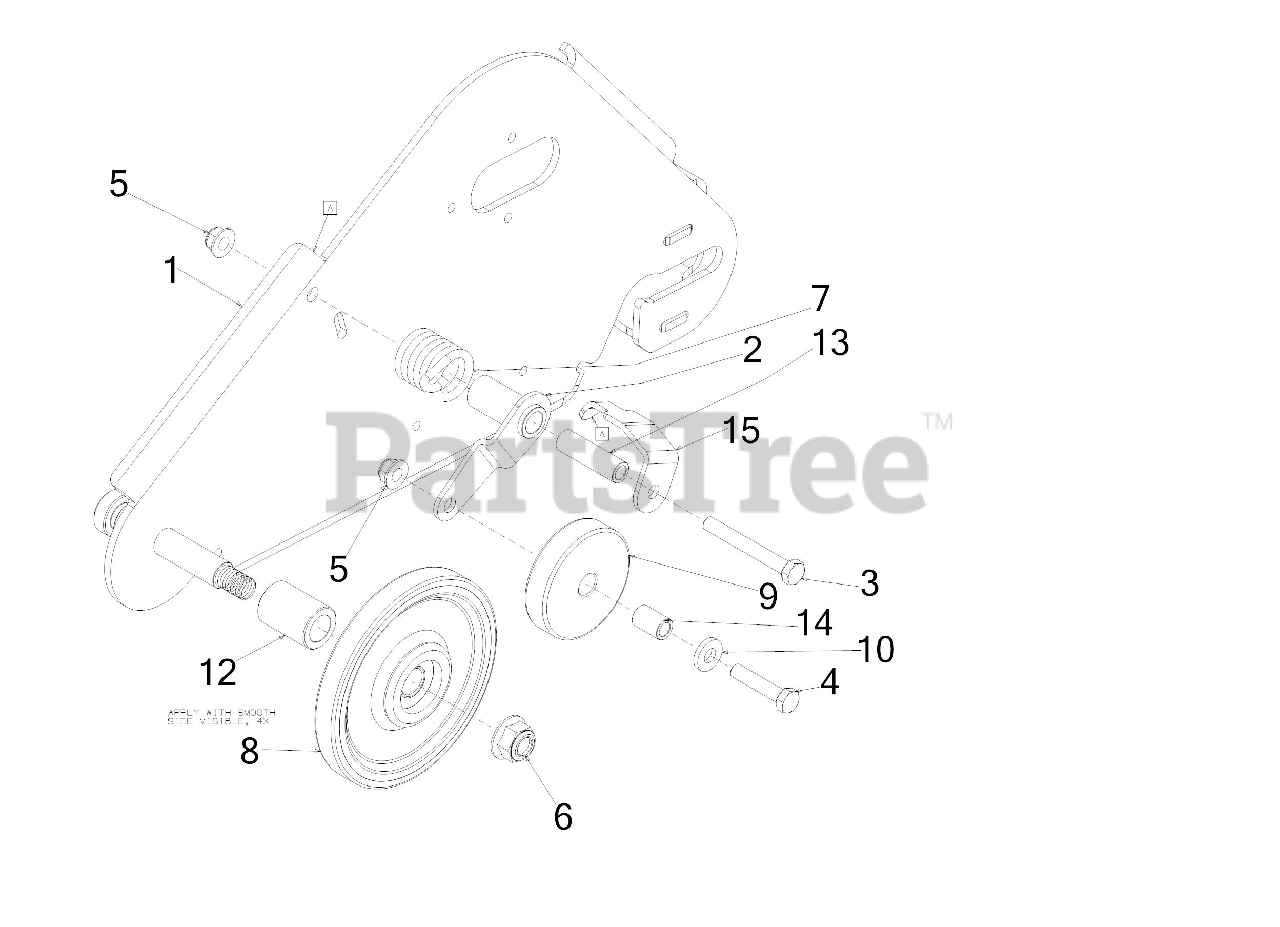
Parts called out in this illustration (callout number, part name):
1	PLATE ASSEMBLY-TRACK (LH)
2	TENSION BRACKET
3	SCREW 5/16-18 x 2.5 GR 5
4	SCREW 5/16-18 x 1.5 LG
5	FLANGE LOCK NUT 5/16-18
7	TORSION SPRING
8	WHEEL-5.00 OD BB
9	WHEEL-TRACK TENSION
10	FLAT WASHER
13	SLEEVE .33X.50X1.73 LG
14	SLEEVE .33X.50X.75 LG
